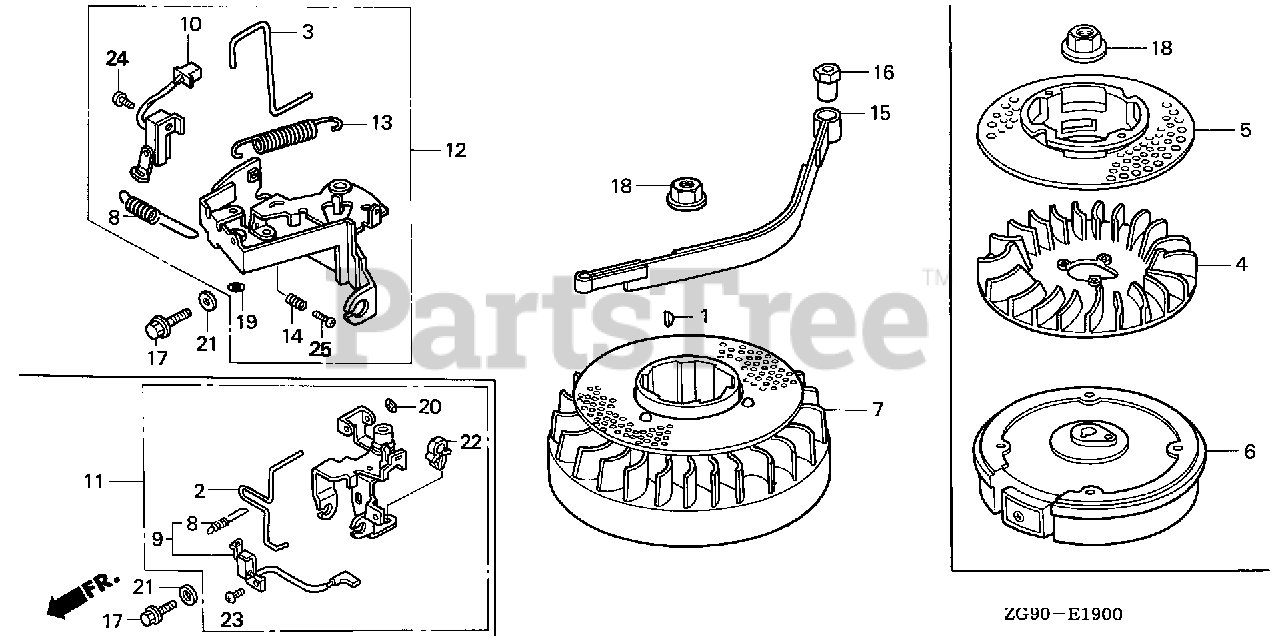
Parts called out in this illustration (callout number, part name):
1	KEY, SPECIAL WOODRUFF (25X18)
7	FLYWHEEL ASSY.
18	NUT, SPECIAL (14MM)
